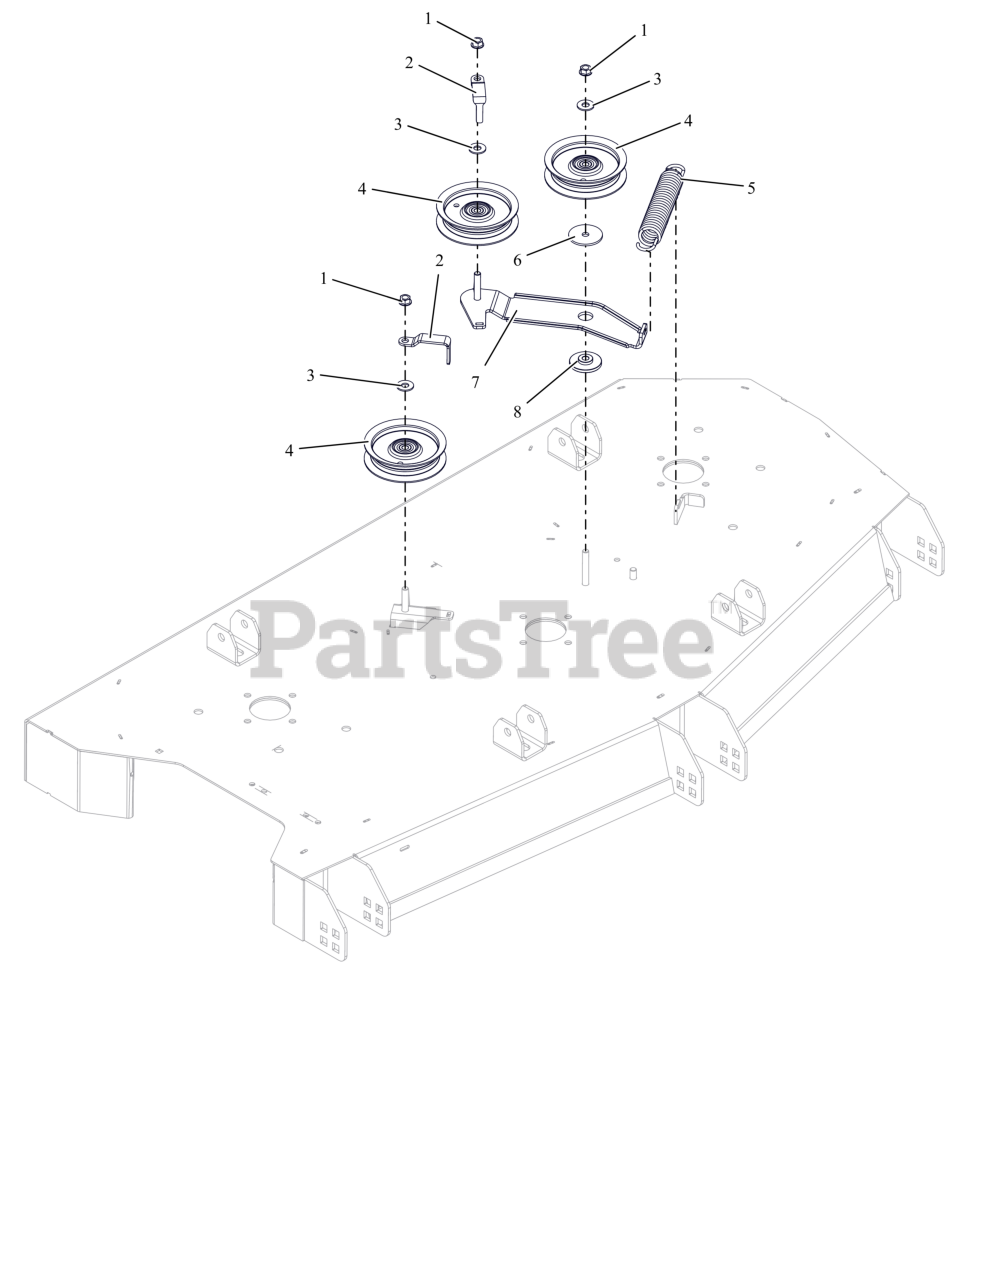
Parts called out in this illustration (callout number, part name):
1	NUT-LK-CTR-FLG .375-16 GF ZCC
2	FINGER, BELT (BLACK)
3	WSHR,FLT .438X1.00X.083 ZCC
4	IDLER, FLAT - 4.06" X .75"
5	SPRG, EXTENSION .170X1.385X6.7
6	WSHR-FL-STL 0.406X2X0.125 ZCC
7	ARM- TENSIONER
8	BSHG-FLG .406X.88X.43X.25
